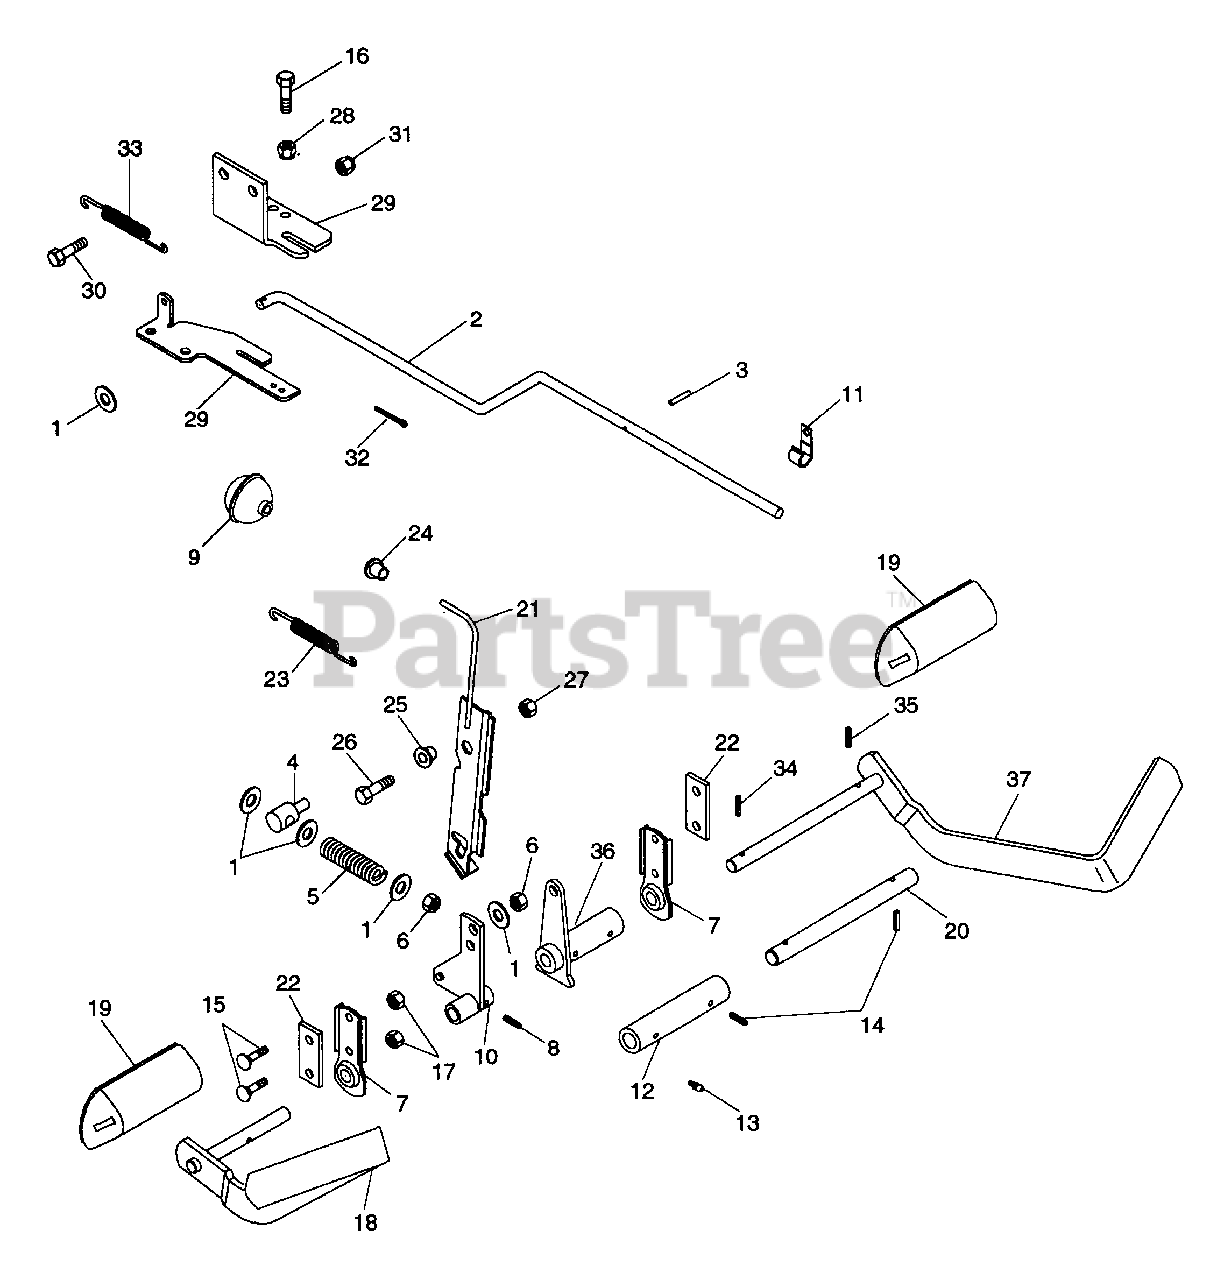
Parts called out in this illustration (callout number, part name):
1	WSHR-FL-STL.406X.812X.065PL
2	BRAKE ROD
3	PIN-ROLL .125X.75
5	SG-COMP .125X.74X6.27 WLD 85
6	NUT-LK-CTR .375-16 GR A PL
7	ROD END BRG. ASSY (CD1508P)
8	PIN-GRV .188X.75 TP A
9	PUSH/PULL CONTROL KNOB
10	BRAKE ARM
11	J-CLAMP
12	TUBE .504 X 1.00 X 3.46
13	SPIN DRIVE ZERK FITTING
14	PIN-ROLL .188X.88
15	BLT-RDHDSQNK .25-20X.75 GR5PL
16	SCR-MCH 10-24X.62 P/HD
17	NUT-LK-CTR .250-20 PL
18	BRAKE PEDAL
19	PEDAL COVER
20	PIVOT ROD
21	PARKING BRAKE LEVER
23	SG-TENS .051X.44X4.38 WLD 7.5
24	SNAP BUSHING-.437
25	BSHG, FLG .325X.499X.26X.88
26	BLT-HEX .31-18X.75 PL GR5
27	NUT-LK .312-18 GR A PL
28	NUT-LK 10-24 NY PL
29	BRAKE GUIDE
30	BLT-HEX .25-20X.75 PL GR2
31	NUT-LK-NYL .250-20 PL
32	PIN-COTR .09X.75 PL
33	SG-TENS .080X.73X3.06 WLD 20
34	PIN-GRV .188X1.25 TP A
35	PIN-ROLL .188X.75
36	CLUTCH ARM
37	CLUTCH PEDAL
